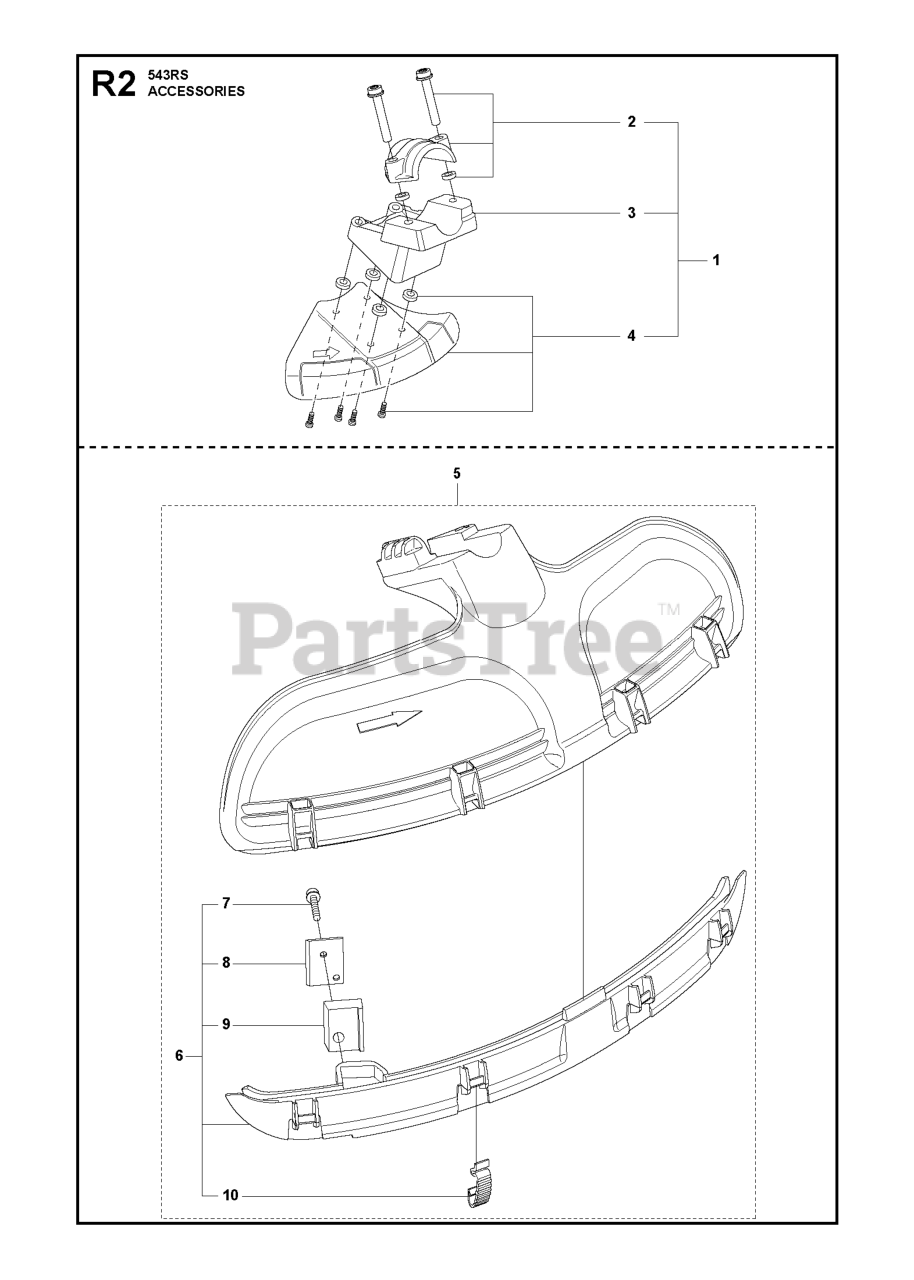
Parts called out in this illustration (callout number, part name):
5	COMBI PROTECTOR
6	SPLASH GUARD
8	LINE CUTTER
9	DISTANSBLOCK
